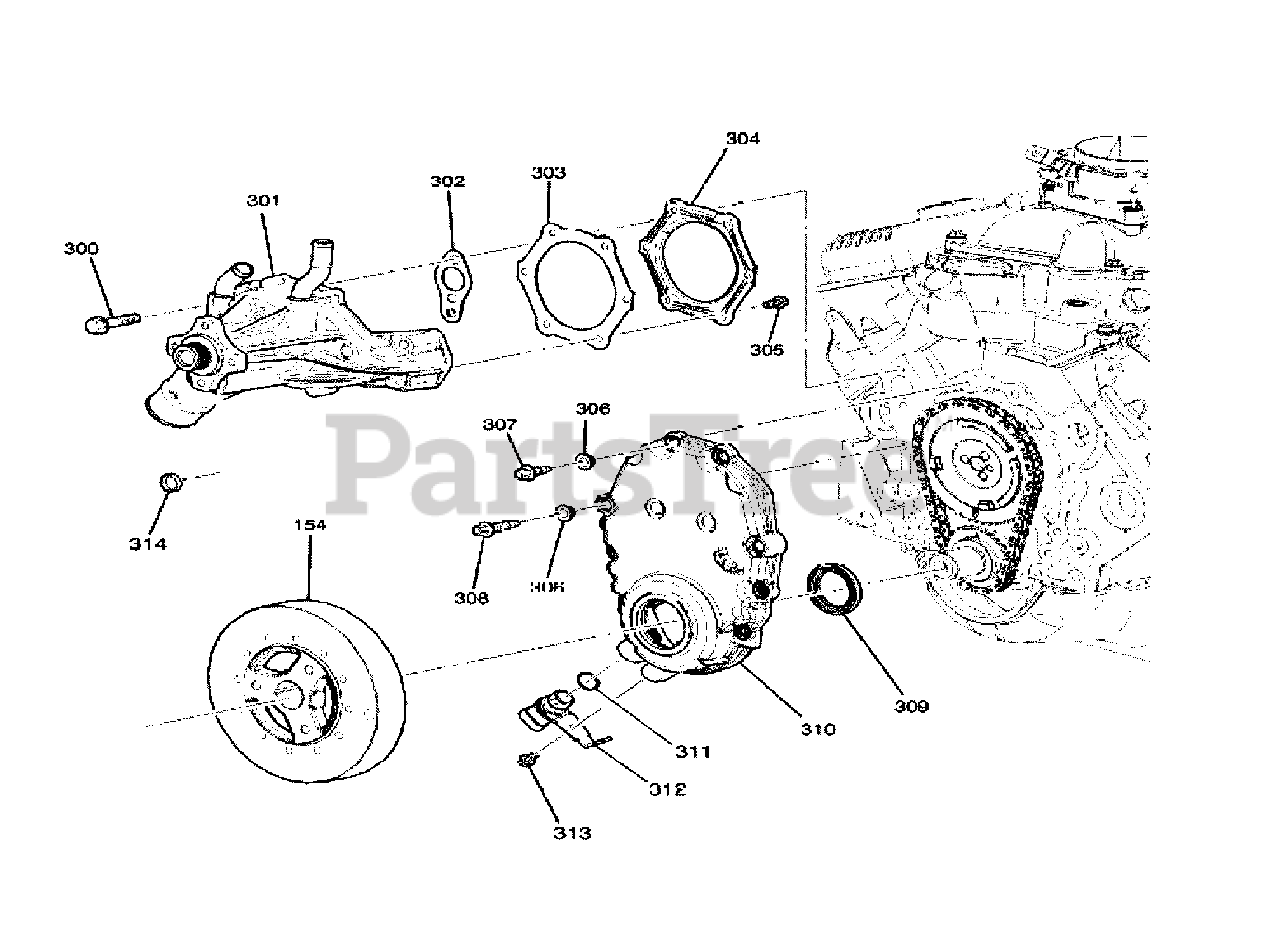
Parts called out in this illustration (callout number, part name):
300	* BOLT
301	WATER PUMP WITH GASKET
303	GASKET
304	* COVER
305	* BOLT
306	* GROMMET
307	* BOLT
308	* BOLT
310	* COVER
311	* SEAL
313	* BOLT
314	* PLUG
